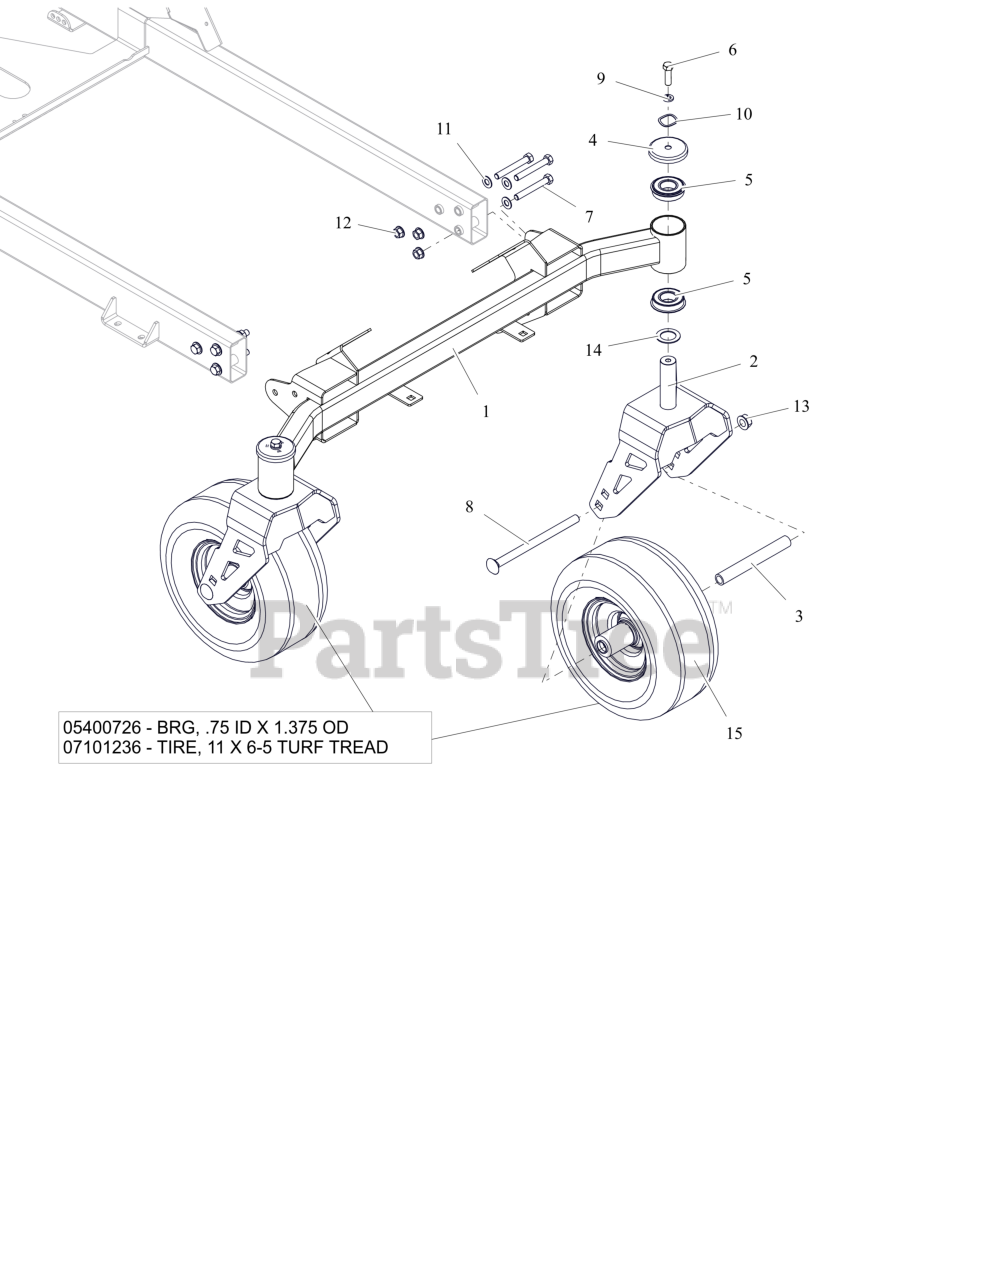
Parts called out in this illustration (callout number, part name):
1	WMT-FRONT AXLE-X/XL
2	WLDMT, CASTER FORK-XL (ORANGE)
3	SPACER, FRONT WHEEL (WIDE 6.0)
4	SHIELD, AXLE BEARING
5	BEARING, BALL -2.000 OD X 1.000 ID X .5625 W/RING
6	BLT, HEX .38-16X1.25 G5 ZCC
7	BLT, HEX .38-16X2.75 G8 ZCC
8	BLT, RHSN .50-13X7.50 G5 ZCC
9	WSHR,LK-REG .375X.094 ZCC
10	WSHR-WAVE 1.0X1.25X.028 .145FH
11	WSHR,FLT-HRD.406X.812X.055 MZC
12	NUT-LK-TOP-FLG .375-16 GG ZCC
13	NUT-LK-TOP-FLG .500-13 GF ZCC
14	WSHR-HRD-THRS 1.007X1.542X.062
15	ASM- TIRE/WHEEL 11X6-5
15	BRG, .75 ID X 1.375 OD
15	LAWN TIRE FRONT, 11/6.00-5 SMOOTH
